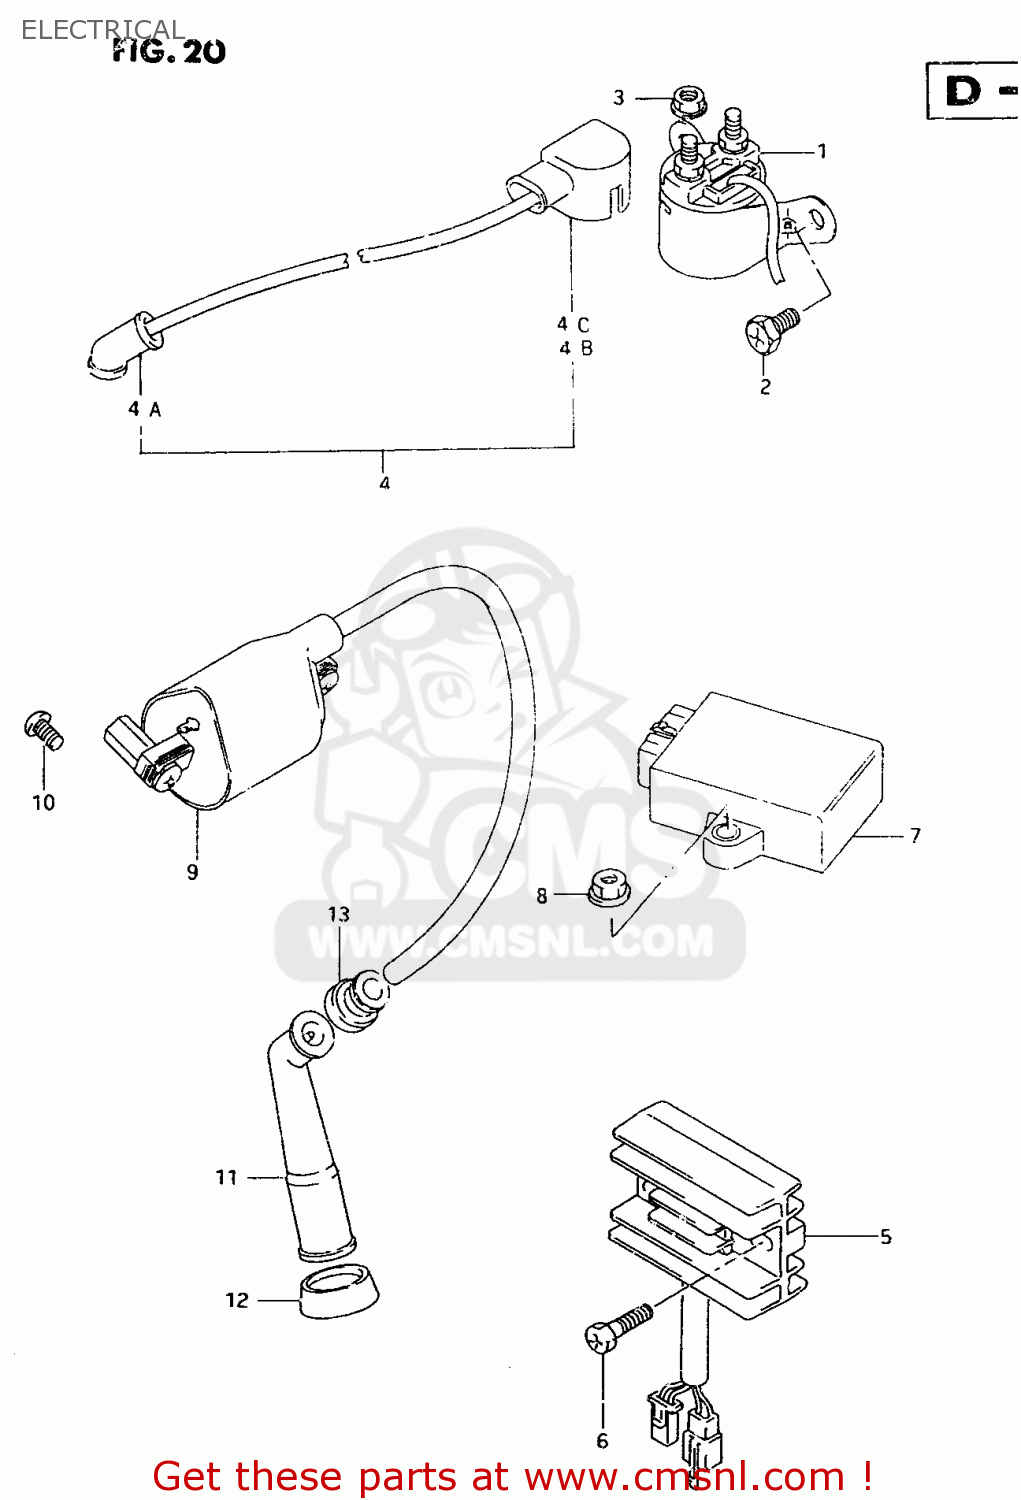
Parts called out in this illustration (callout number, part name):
1	RELAY ASSY,STARTING MOTOR
2	SCREW(6X10)
3	NUT
4	WIRE,STRT.LEAD
4A	CAP,STARTER MOTOR LEAD
4B	CAP,STARTER RELAY TERMINAL
4C	CAP,STARTER RELAY TERMINAL
5	RECTIFIER ASSY
6	BOLT(6X20)
7	IGNITOR UNIT
8	NUT
9	COIL ASSY,IGNITION
10	SCREW
11	CAP ASSY,SPARK PLUG
12	SEAL,SPARK PLUG CAP
13	SEAL,HIGH TENSION CORD
